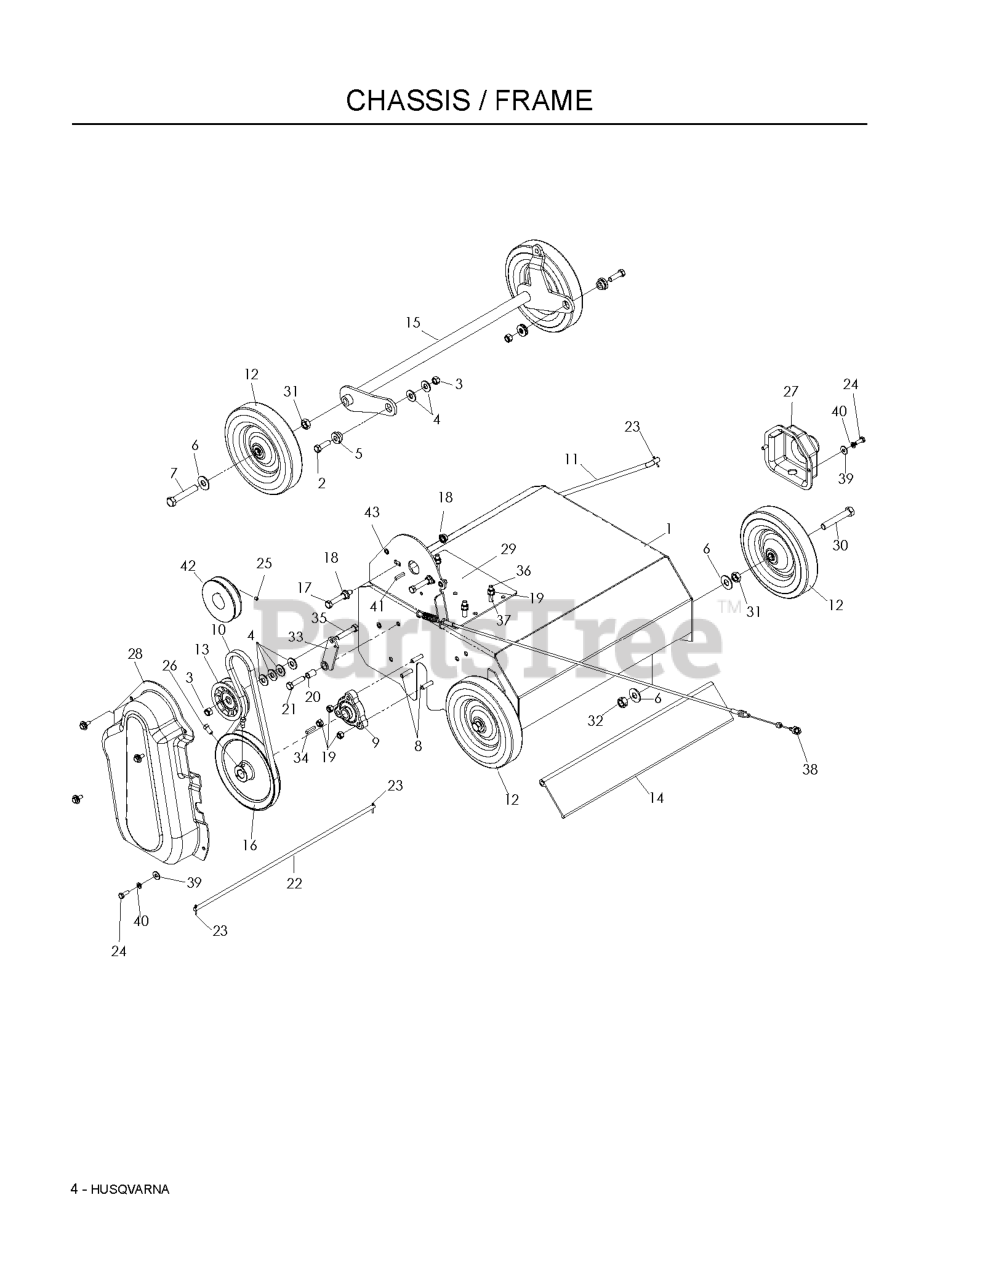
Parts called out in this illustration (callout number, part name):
1	KIT, BODY W/DECALS
2	HCS 3/8C X 1 1/4 GR5
3	NUT 3/8-16 NYLOC
4	WASHER 3/8 FLAT
5	BUSHING RAKE
6	WASHER 1/2 FLAT
7	HCS 1/2C X 2 3/4
8	HCS 5/16C X 1 1/4
9	BEARING, FLANGED
10	BELT, DRIVE RAKE/SLICER DFS
12	WHEEL 8 X 1 3/4 RAKE
13	PULLEY, IDLER RAKE & ZTR
14	DEFLECTOR SHIELD
15	FRONT AXLE ORANGE
16	PULLEY, MAIN SHAFT
17	HCS 3/8C X 2 1/2
18	NUT 3/8C WHIZ
19	NUT 5/16 NYLOC
20	BEARING, ONLITE RAKE/DT
21	HCS 3/8C X 1 1/2
22	DEFLECTOR ROD
23	COTTER PIN 3/32 X 3/4
24	HCS 1/4C X 3/4 HCS
26	SCREW 5/16C X 5/8 SQ HEAD
27	SHAFT GUARD
28	BELT GUARD
29	BACKING PLATE, BLUE
30	SCREW, 1/2C X 3 HEX CAP
31	NUT 1/2 HEX JAM
32	NUT 1/2-13 HEX CNTRLK GR 5 ZD
33	IDLER, ARM, BLACK
34	KEY, 3/16 SQUARE
35	HCS 3/8C X 2
36	HCS 5/16C X 1 3/4
37	WASHER.LOCK.HVY.HLCL.SPR.5/16
38	CABLE POWER RAKE
39	WASHER 1/4 FLAT
40	LOCKWASHER 1/4"
41	KEY, 3/16 SQUARE
42	ENGINE PULLEY - 5.5 HP
43	KNURLED INSERT
